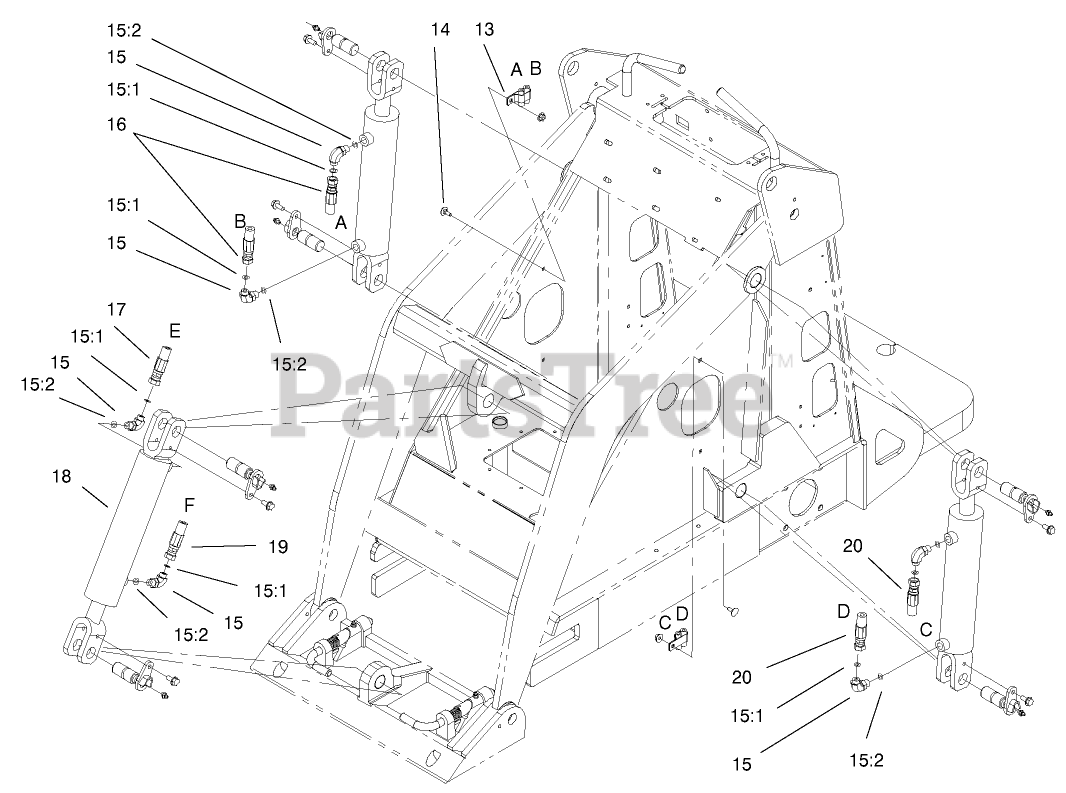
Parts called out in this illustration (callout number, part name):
13	CLAMP-R, DOUBLE
14	BOLT-CARR
15	FITTING-ELBOW 90
15:1	O-RING
15:2	O-Ring
16	HOSE-HYD
17	HOSE-HYD
18	Cylinder-Hydraulic
19	HOSE-HYD
20	HYD HOSE ASM
